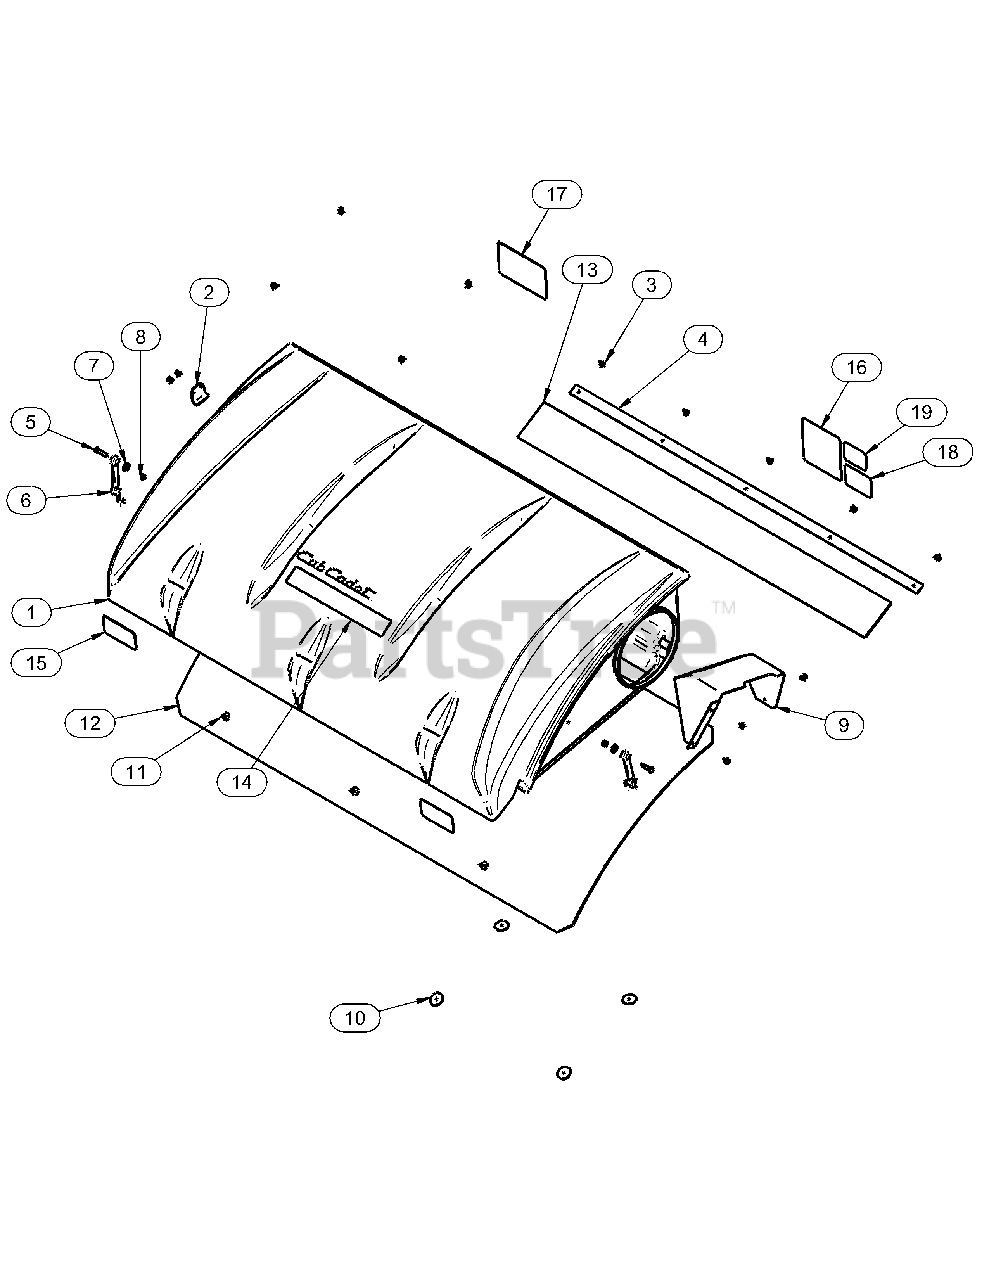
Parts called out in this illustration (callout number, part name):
1	Pro 3 Bagger Top
2	Hinge Stop Pl.
3	Black Plastic Rivet
4	Dust Guard Brace
5	1/4"-20 X 1-1/4" Carriage Bolt
6	Short Rubber Strap W/ S Hook
7	1/4" Flat Washer .75 Od X .314 Id X .060 T
8	1/4"-20 Nyloc Nut
9	Grass Deflector
10	3/16" X 1-1/2" Fender Washer, Z
11	Black Panel Retainer
13	Dust Guard
14	Cub Cadet Logo
15	2" X 4" Red Reflector Label
16	Warning - Turn Off Blower Label
17	Made In Usa Label
18	Important Check Hoses
19	Warning - Use Hearing Protection
